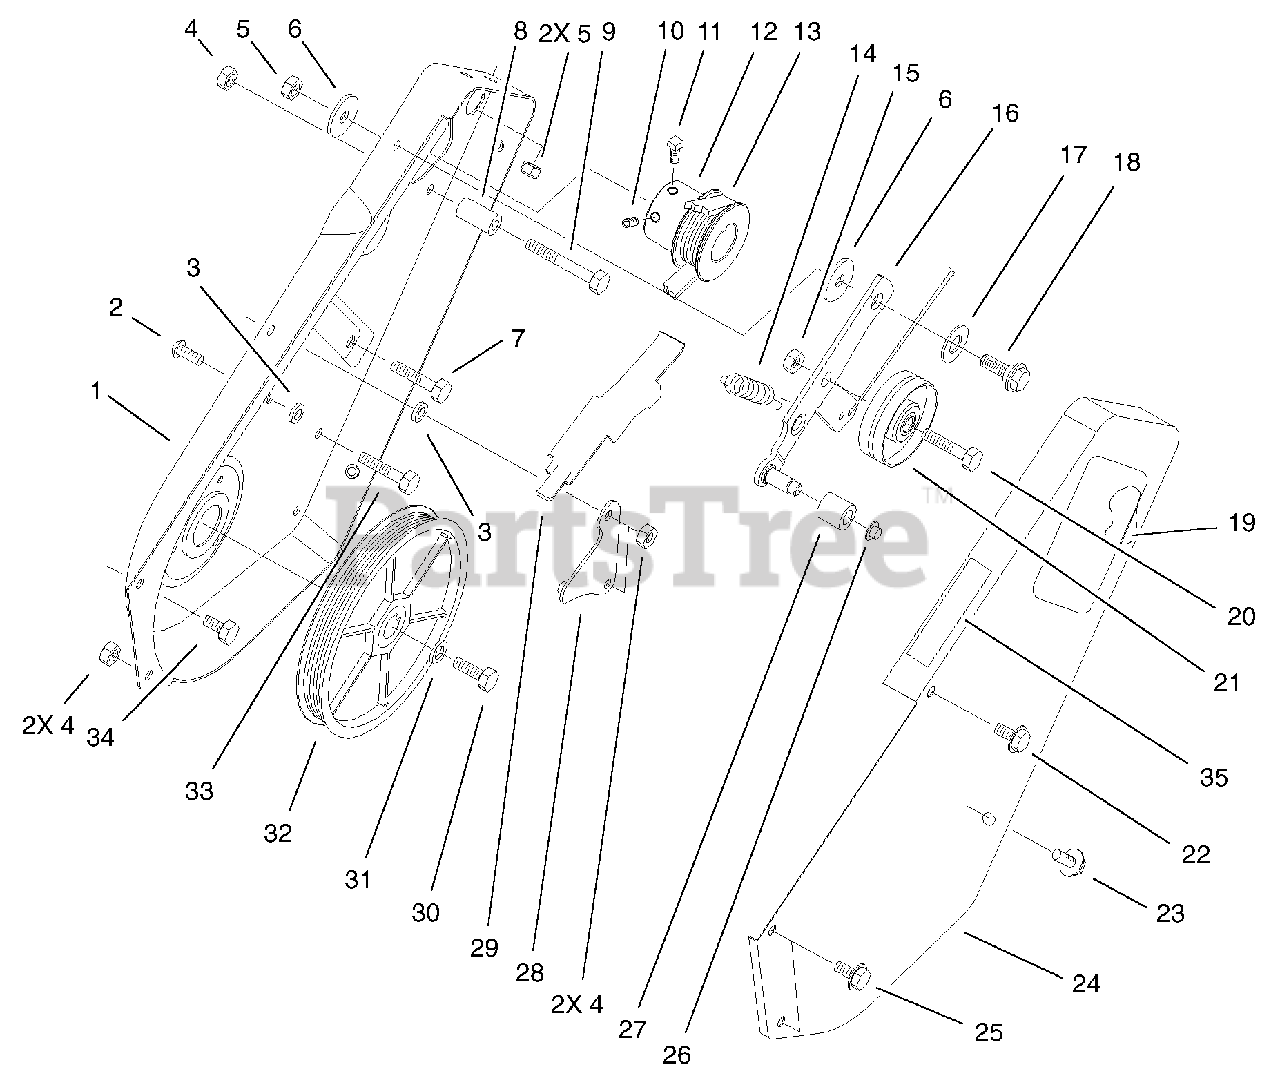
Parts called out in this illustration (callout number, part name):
1	PLATE-SIDE, LH
2	SCREW-HSBH
3	SPACER-PLATE, PIVOT
4	NUT-LOCK, NI
5	NUT-LOCK, NI
6	WASHER-PIVOT
7	SCREW-HH
8	SLEEVE-GUIDE, BELT
9	SCREW-HH
10	SCREW-HSH
11	SCREW-SQH
12	PULLEY-ENGINE
13	BELT-DRIVE
14	SPRING-EXTENSION
15	NUT-LOCK, CONE
16	IDLER ARM ASM
18	SCREW-SHOULDER
20	SCREW-HH
21	PULLEY-IDLER
22	SCREW-HWH, TAP
24	COVER-DRIVE
27	ROLLER-BRAKE
28	PIVOT PLATE ASM
29	BRAKE-ARM
30	SCREW-HH
31	WASHER-BELLEVILLE
32	PULLEY ROTOR ASM
33	SCREW-HH
34	SCREW-SHH
35	DECAL-WARNING
